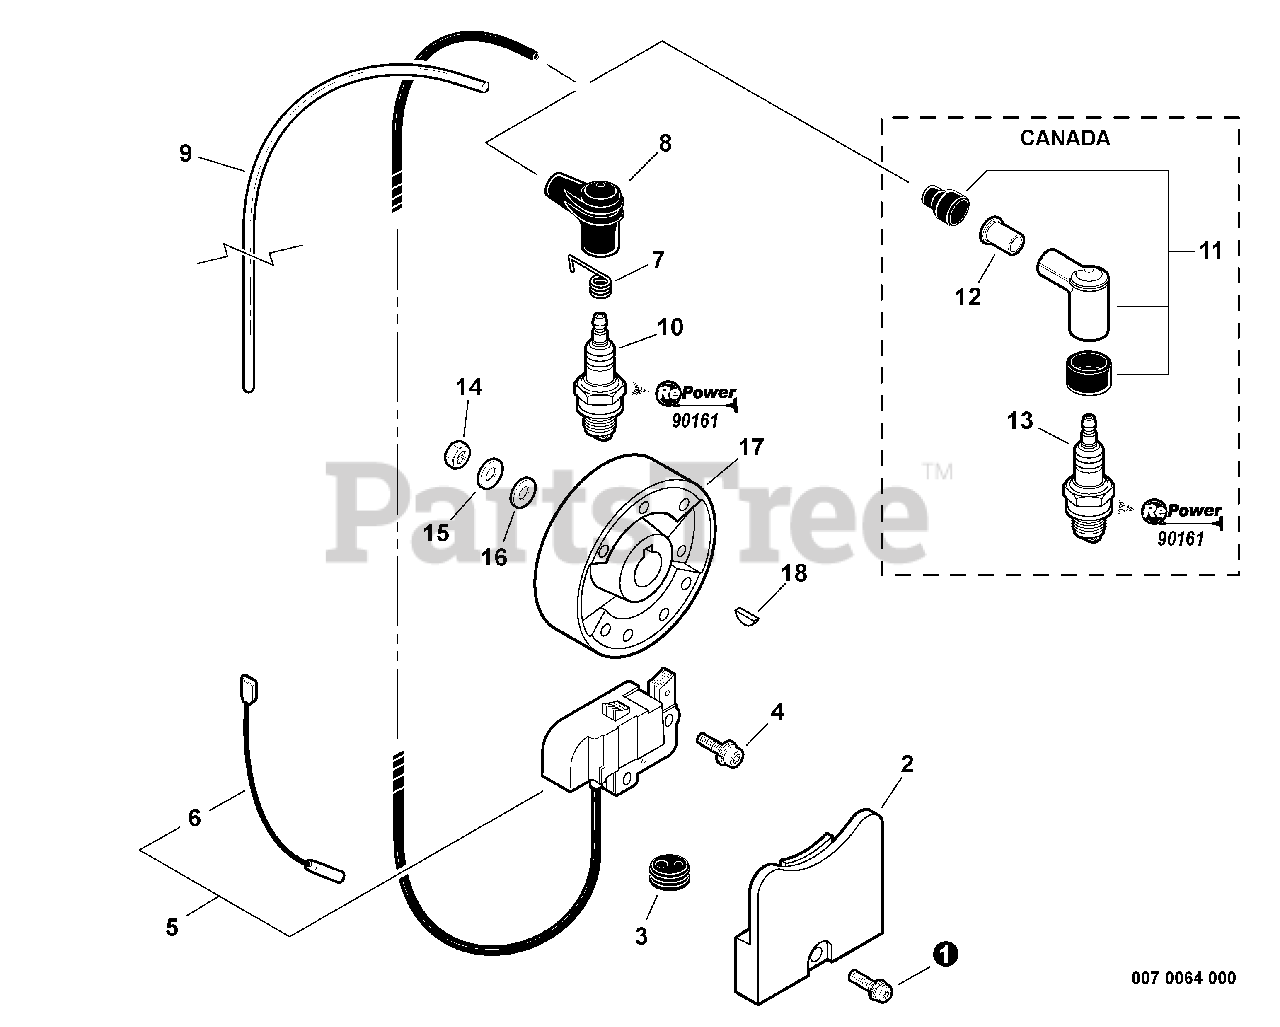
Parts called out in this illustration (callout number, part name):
1	SCREW - 5X18
2	COVER, DUST
4	SCREW - 5X18
5	COIL, IGNITION
6	LEAD - IGNITION
7	TERMINAL, SPARK PLUG CAP
8	CAP, SPARK PLUG
9	TUBE - VINYL
10	SPARK PLUG -- BPM-8Y
11	CAP, SPARK PLUG
12	ADAPTER, SPARK PLUG CAP
13	SPARK PLUG -- BPMR-8Y
14	NUT - 10
15	LOCKWASHER - 10
16	WASHER - 10
17	FLYWHEEL
18	KEY - 3X14
19	RePower TUNE-UP KIT
